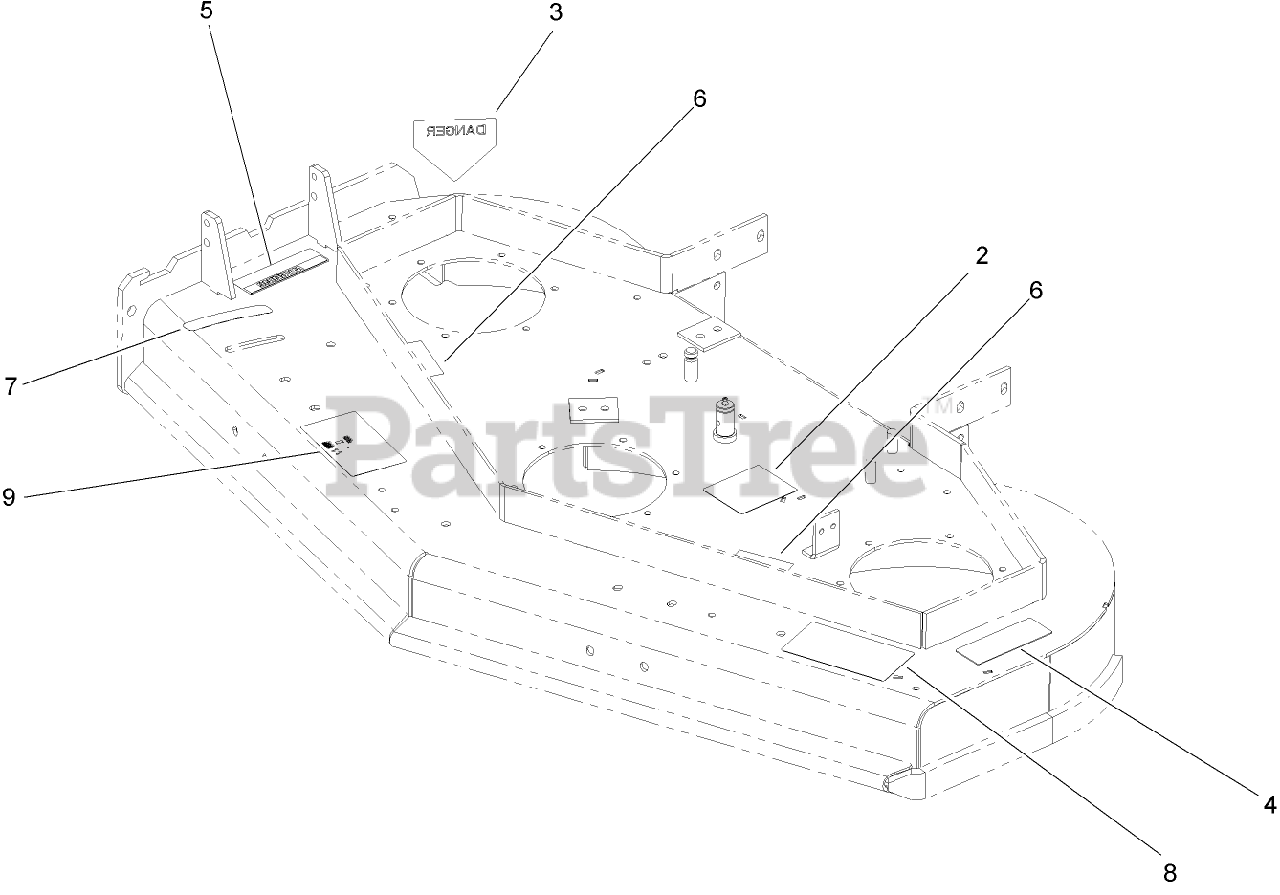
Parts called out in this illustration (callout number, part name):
2	DECAL-ROUTING, BELT
3	DECAL-DANGER
4	DECAL-TORQUE, BOLT
5	DECAL-WARNING
6	DECAL-COVER, MISSING
7	DECAL-SETTING, BAFFLE
8	DECAL-DANGER, THROWN OBJECT
9	DECAL-ADJUSTMENT, BAFFLE
